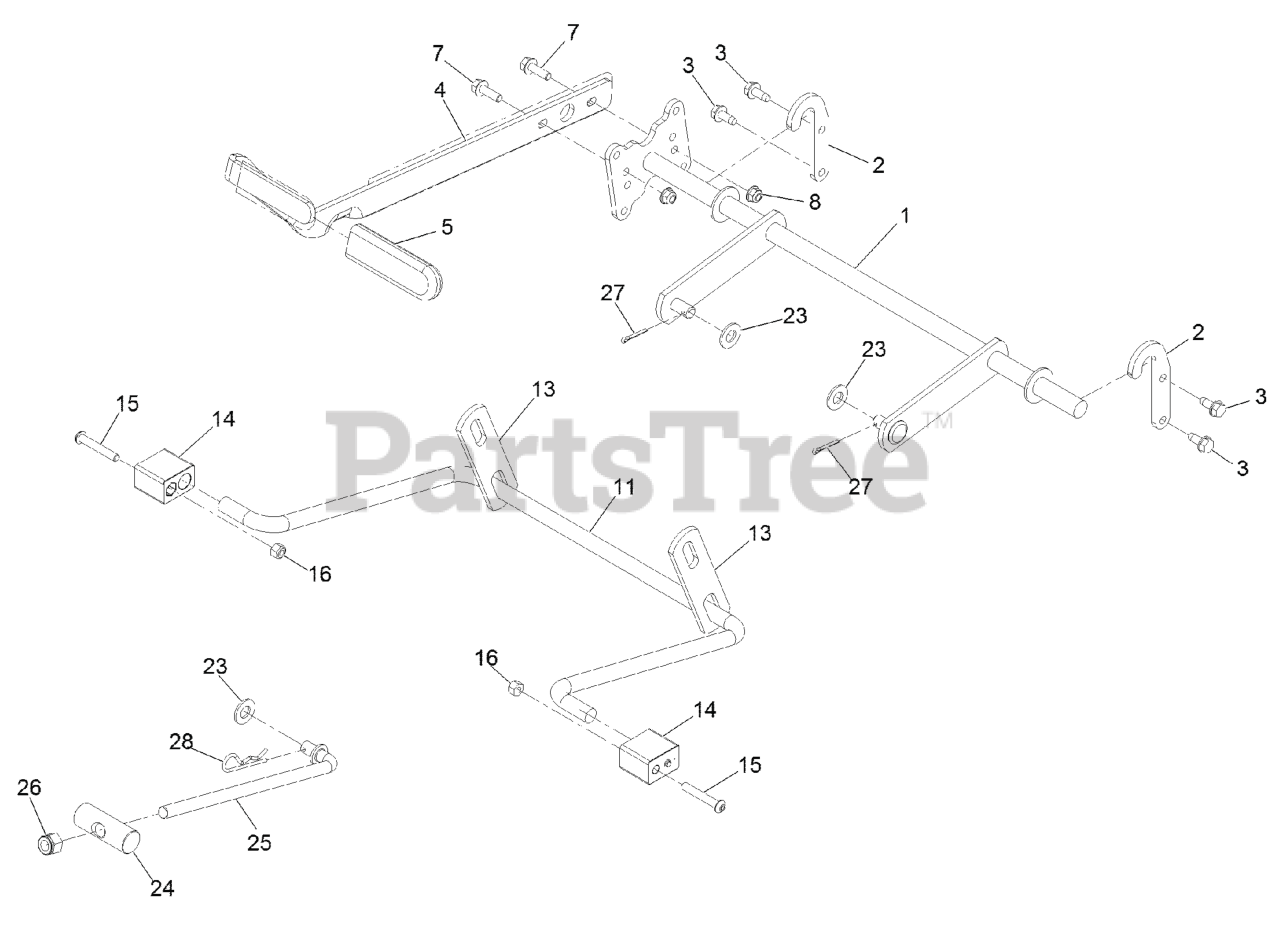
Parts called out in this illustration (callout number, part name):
1	LIFT-DECK, NARROW
2	BRACKET-LIFT
3	Screw-HWH 5/16-18 X 3/4 Tf
4	HANDLE-DECK LIFT
5	GRIP-LEVER
7	SCREW-HHF
8	NUT-HF, NI
11	Arm-Lift, Rear
13	LINK-LIFT
14	BLOCK-PIVOT
15	SCREW-HSBH
16	NUT-LOCK, NI
23	WASHER-FLAT
24	PIN-PIVOT
25	ROD-MOUNT, DECK
26	NUT-HEX
27	PIN-COTTER
28	PIN-COTTER
